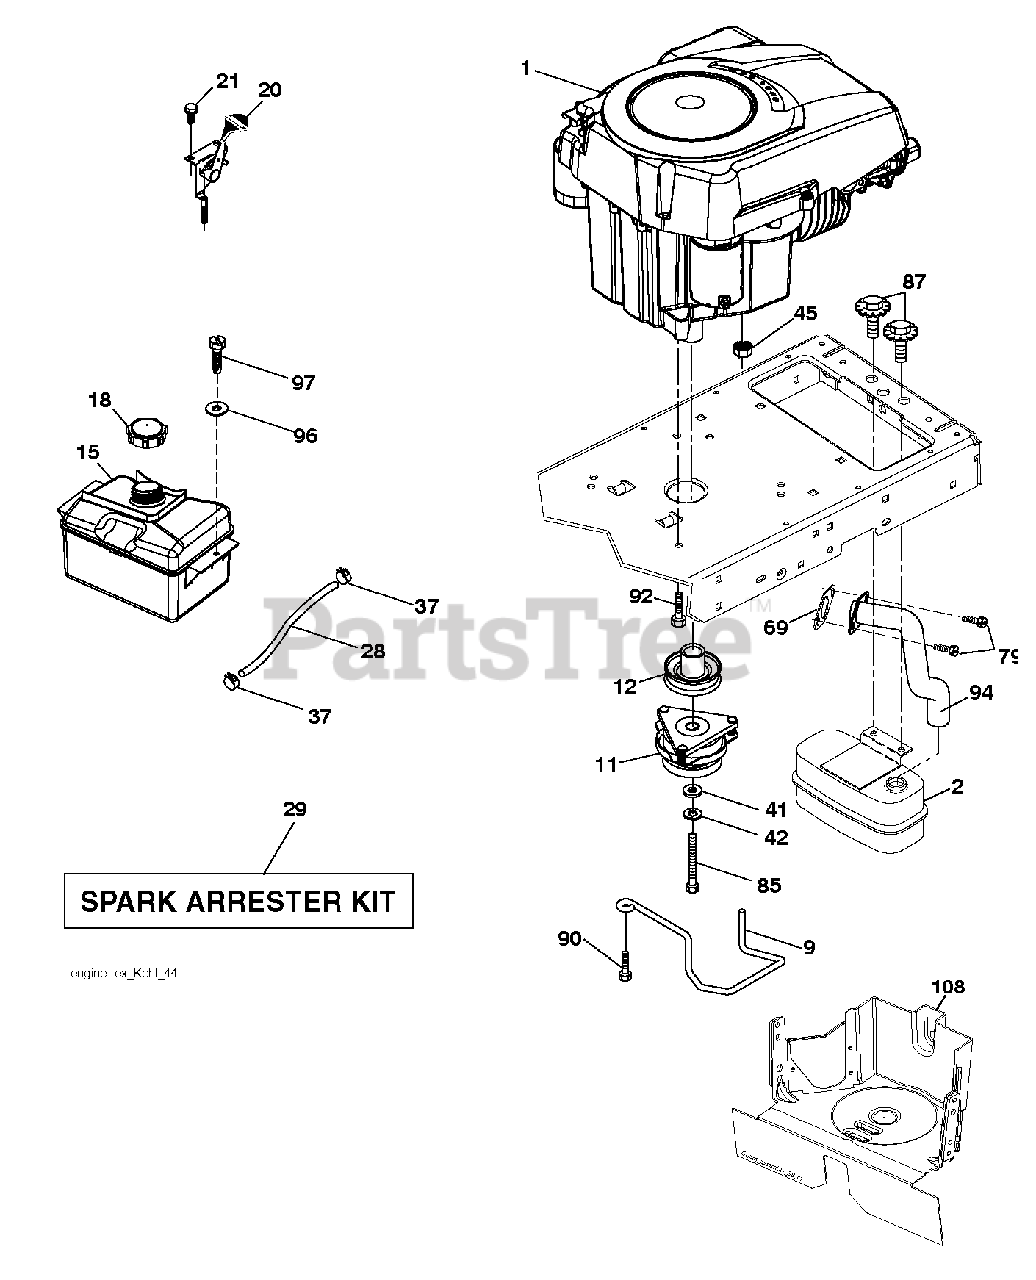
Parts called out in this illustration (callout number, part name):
2	MUFFLER.SINGLE.CYL.KOHL/B&S
9	KEEPER.BELT.ENGINE.4.2
11	CLUTCH.ELECTRIC.LT.48"*
12	PULLEY.ENGINE.TUFFTORQ
15	RP TANK FUEL FRT 1.5 GAL
18	CAP ASM.FUEL.2.25"FR.
20	CONTROL.TH/CK.C.
21	SCREW.#10 X 0.750.BOS
28	LINE.FUEL.20
29	KIT.SPARK ARRESTOR 794945 B&S
37	HOSE CLAMP
42	LOCKWASHER
45	NUT
69	GASKET.EXHAUST.KOHLER
79	SCREW.SOCKET HD.5/16-1
85	BOLT HEX 7/16-20X4-1/4"
87	Bolt, 5/16-18 X 1-3/4
90	SCREW 3/8-16X1
92	SCREW 3/8-16X1
94	RP.TUBE.EXHAUST.KOHL.COURAGE
97	SCREW HEXWSHR 1/4-20X3/4
108	COVER PULLEY
